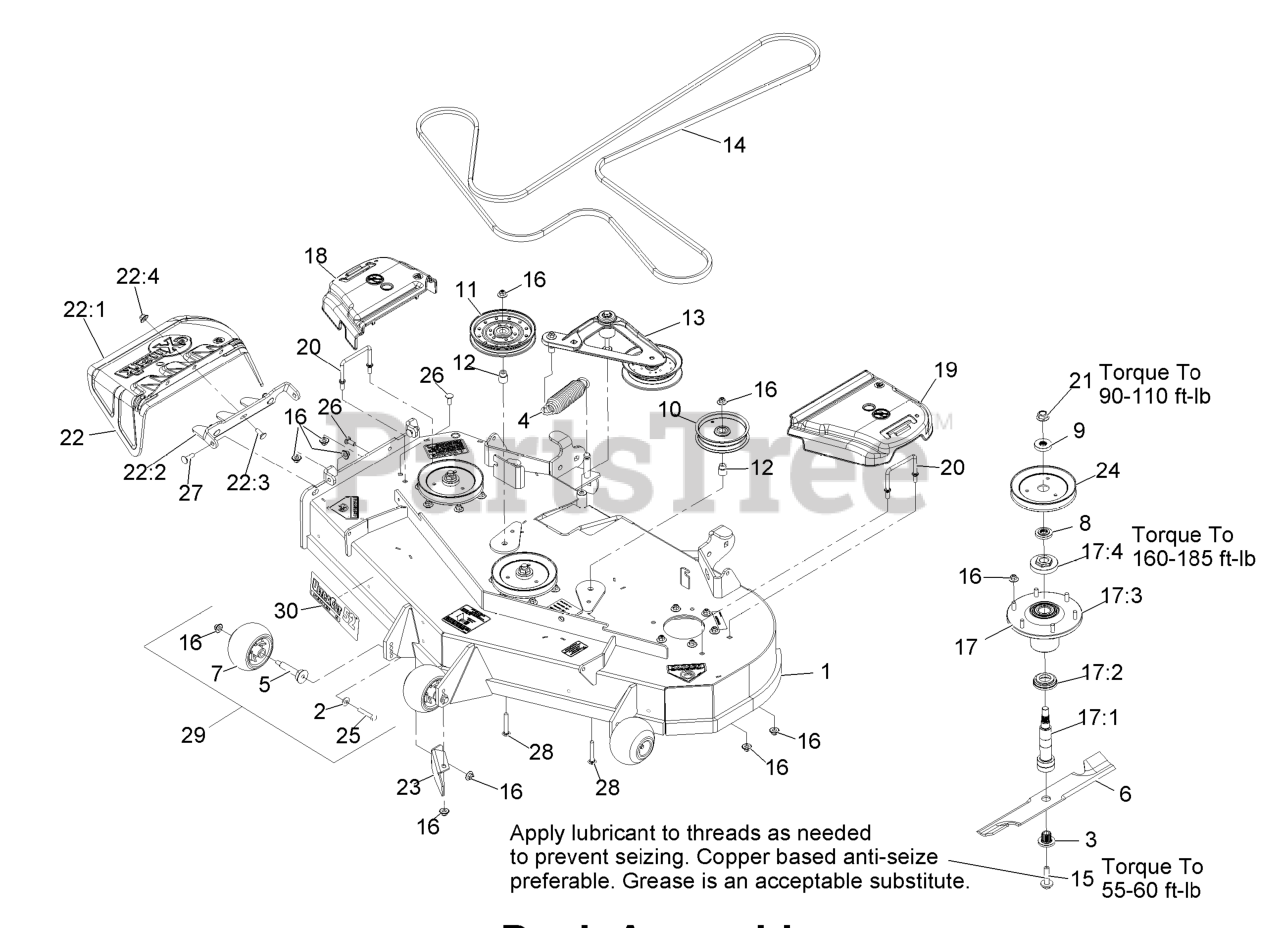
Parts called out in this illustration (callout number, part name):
1	ASM,DECK W/ DECALS 52
2	WASHER-BELLEVILLE
3	BUSHING,SPLINED
7	ROLLER-SCALP, ANTI
8	SPACER,SPLINED STEPPED
9	SPACER,SPLINED
10	PULLEY-IDLER
12	BUSHING-IDLER
13	DECK IDLER ASM
14	BELT,V-B X 186.00"
15	SCREW,SEMS 1/2-20 X 2.19
16	Nut-Nyloc 3/8-16 Flg
17	ASM,SPINDLE HOUSING
17:1	GUARD,BOTTOM
17:2	ASM,CUTTER HOUSING
17:3	NUT, SPINDLE 7/8-14
17:4	SPINDLE,DOUBLE SPLINE
18	COVER-BELT, RH
19	COVER-BELT, LH
20	WIREFORM-COVER
21	NUT-FLANGE, CENTERLOCK
22	ASM,DISCHARGE CHUTE
22:1	CHUTE,DISCHARGE
22:2	BRACKET,DISCHARGE CHUTE
22:3	SCREW-CARR
22:4	Nut-Nyloc 3/8-16 Flg
23	BAFFLE,DISCHARGE 52/60
24	SHEAVE,BLADE DRIVE
25	SCREW-HH
26	SCREW-CARR
27	Bolt-Carriage 3/8-16 X 1 1/4
28	SCREW-CARR
30	DECAL,ULTRACUT 52 SERIES
